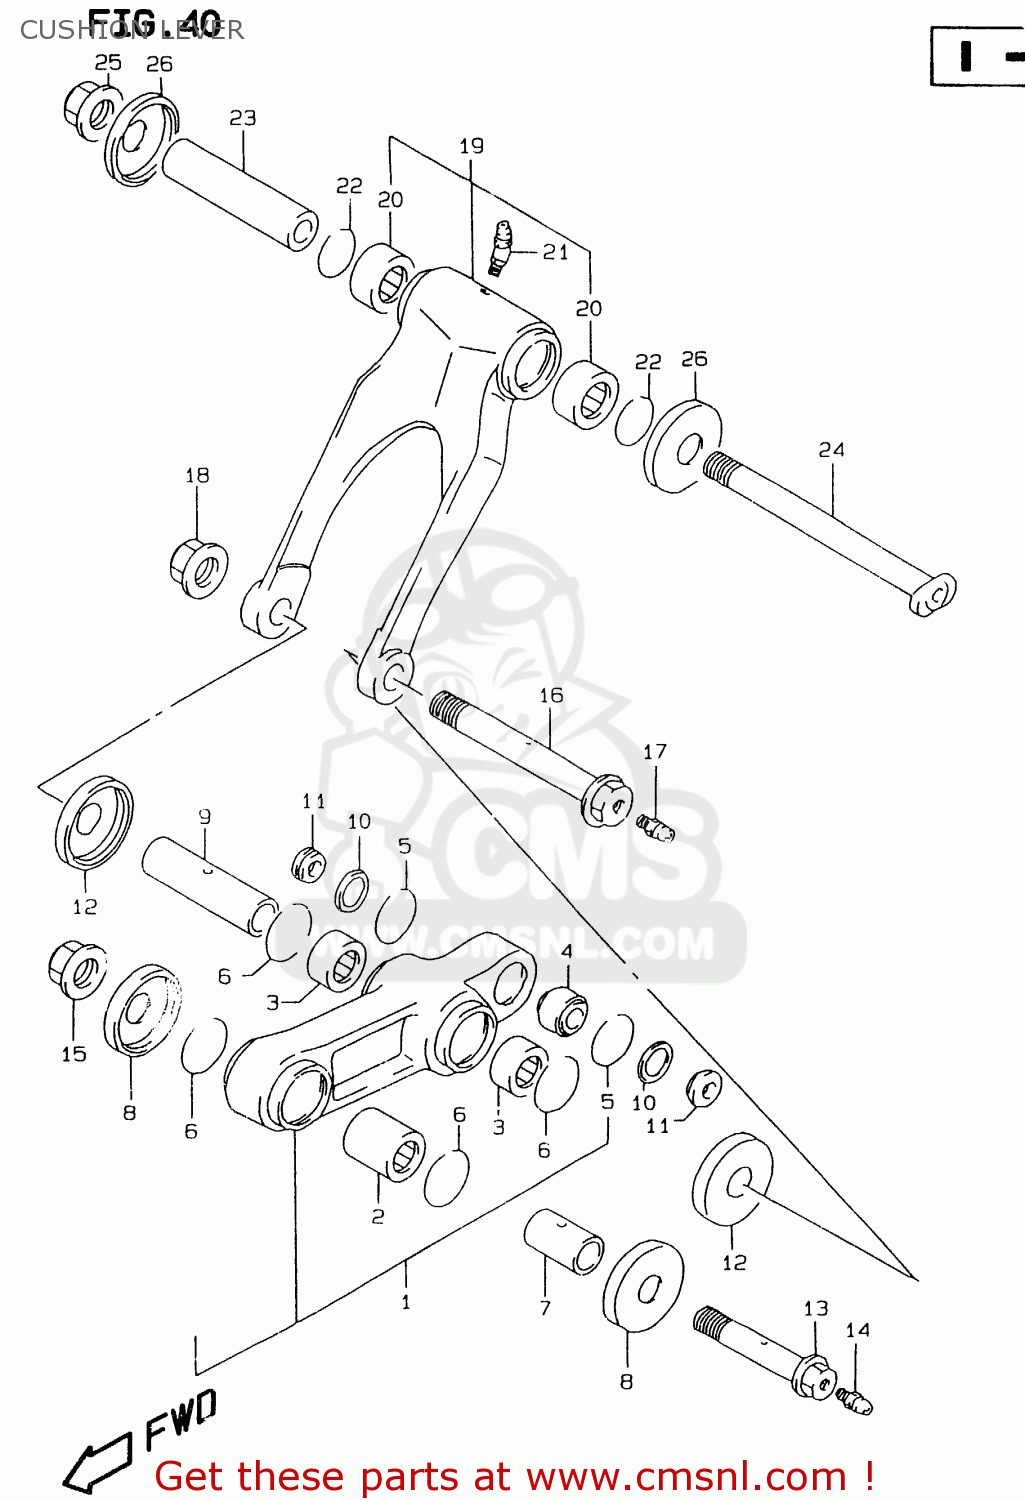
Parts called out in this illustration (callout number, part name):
1	LEVER SET,RR CUSHION
2	BEARING(20X27X25)
3	BEARING(21X27X20)
4	BEARING,RR CUSHION LEVER RR
5	RING,BEARING STOPPER
6	CIRCLIP
7	SPACER,RR CUSHION LEVER FR
8	SEAL,RR CUSHION LEVER FR DUST
9	SPACER,RR CUSHION LEVER CTR
10	SEAL,RR CUSHION LEVER RR DUST
11	SPACER,RR CUSHION LEVER RR
12	SEAL,REAR CUSHION LEVER
13	BOLT SET,RR CUSHION LEVER FR
14	GREASE NIPPLE
15	NUT 12MM
16	BOLT,RR CUSHION LEVER CTR
17	GREASE NIPPLE
18	NUT
19	ROD SET,RR CUSHION LEVER
20	BEARING(21X27X20)
21	NIPPLE,GREASE
22	CIRCLIP
23	SPACER,RR CUSHION ROD
24	BOLT,RR CUSHION ROD
25	NUT
26	SEAL,REAR CUSHION LEVER
